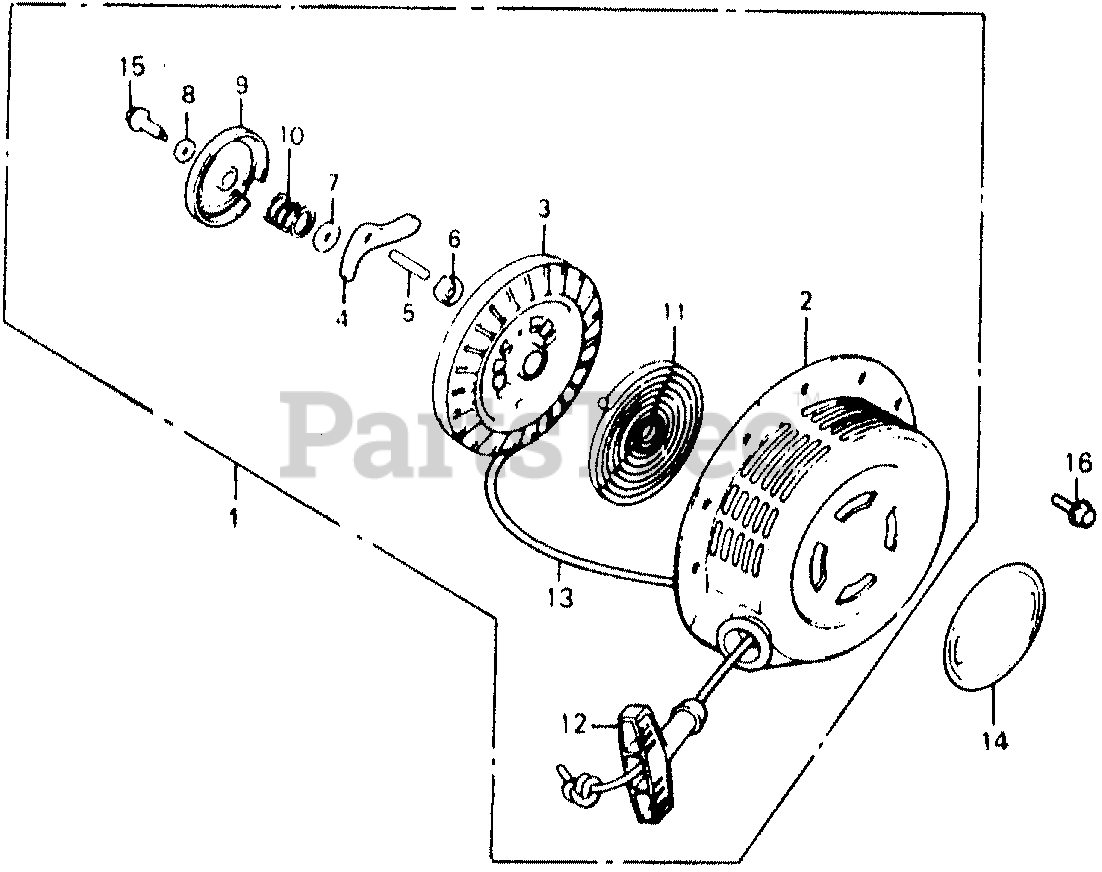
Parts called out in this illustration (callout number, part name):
1	STARTER ASSY., RECOIL *R8* (BRIGHT RED)
3	REEL, STARTER
4	RATCHET, STARTER
5	SHAFT, RATCHET
6	PLATE, GUIDE
7	PLATE A, FRICTION
8	PLATE B, FRICTION
9	COVER, REEL STARTER
10	SPRING, FRICTION
11	SPRING, RETURN
12	GRIP, STARTER
13	ROPE, STARTER (#5X59") (N/A: USE ALT. PNO 08550-ZG921-11)
14	EMBLEM (EXTERNAL-ALERT)
15	BOLT, REEL COVER
16	BOLT, FLANGE (6X8)
